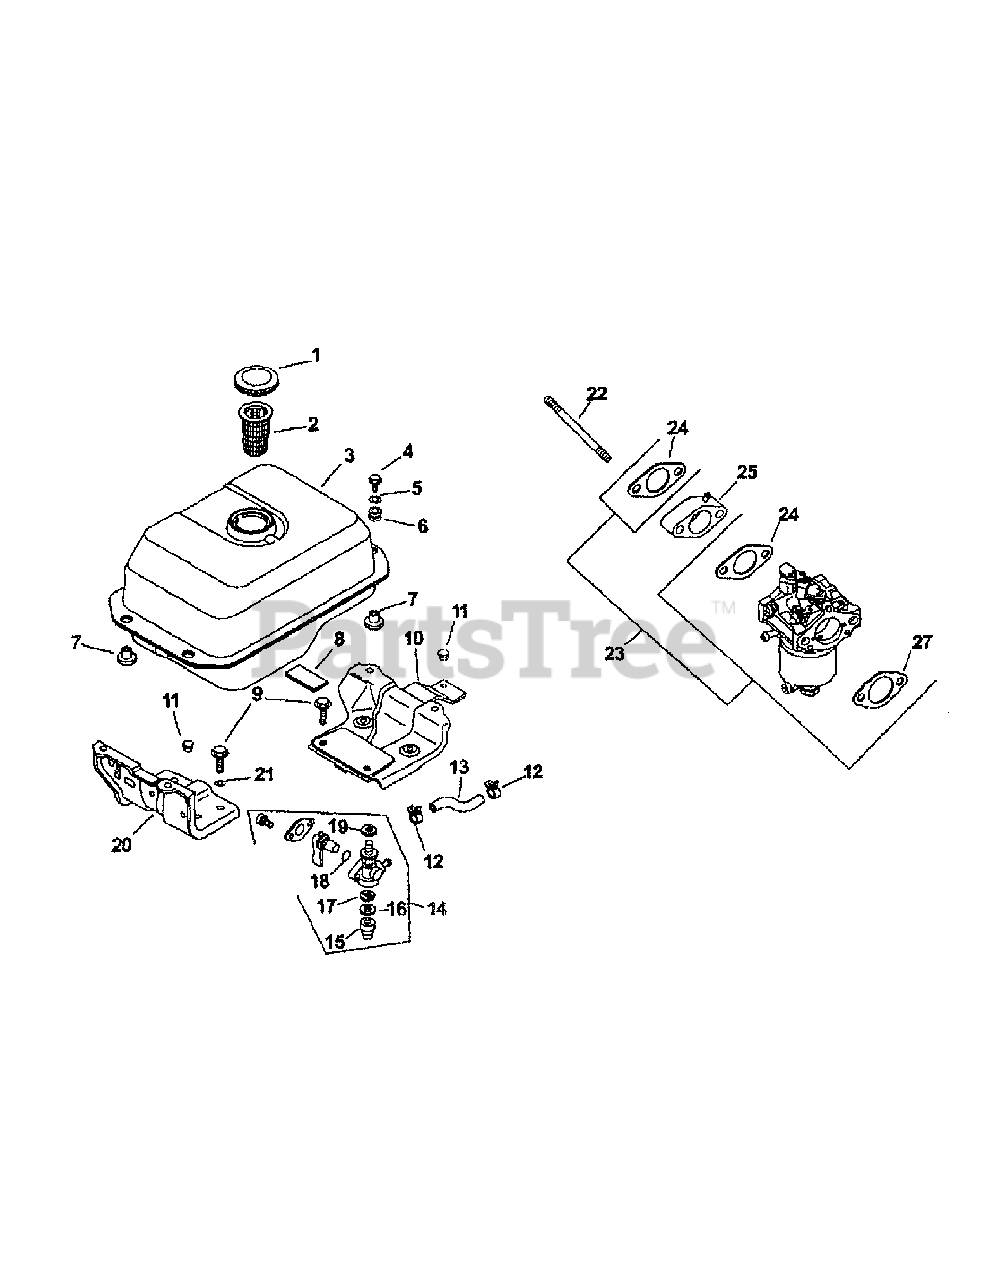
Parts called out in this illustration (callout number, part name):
1	Cap, Fuel Tank
8	Damper, Locating
10	Bracket, Fuel Tank
14	Valve, Fuel Shut Off
16	Gasket
17	Filter, Screen
19	Gasket
20	Bracket, Fuel Tank
22	Stud, Carburetor
23	Carburetor Kit
24	Gasket, Intake
25	Manifold, Intake
27	Gasket, Air Cleaner
